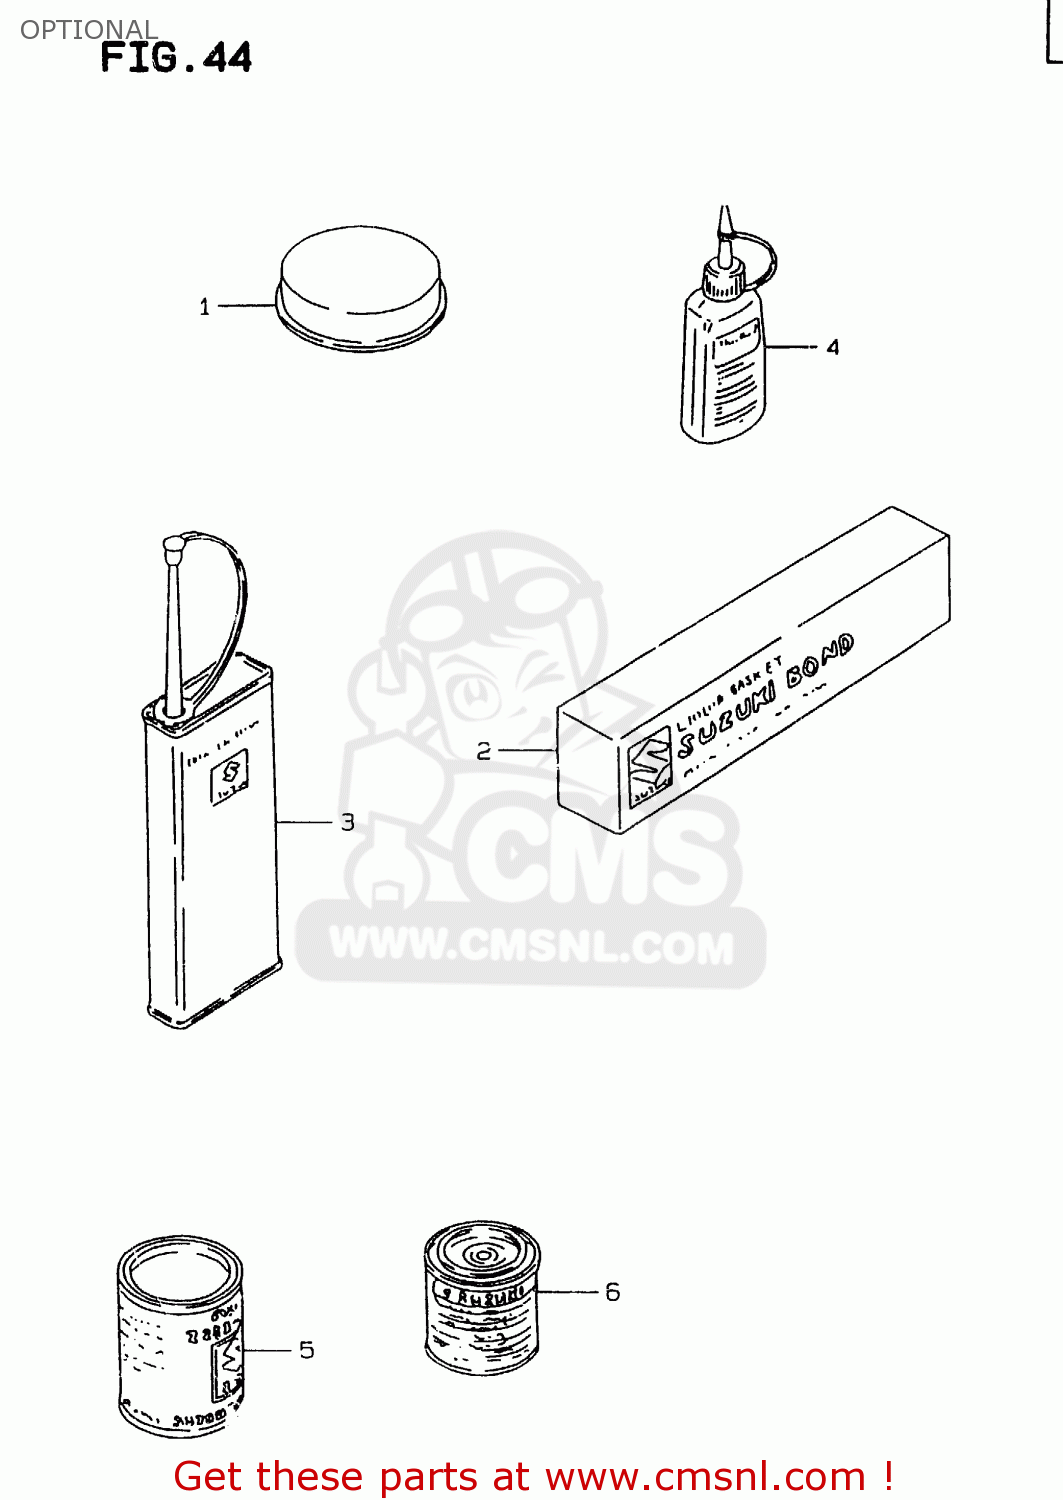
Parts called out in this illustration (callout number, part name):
1	GREASE,PBC FOR BRK PAD 20G
2	BOND 1104
3	THREAD LOCK NO.1401 CLEAR 200G
4	THREAD LOCK NO
5	GREASE(C)EP2 LITHIUM 150G
6	PAINT BLIGHT S
